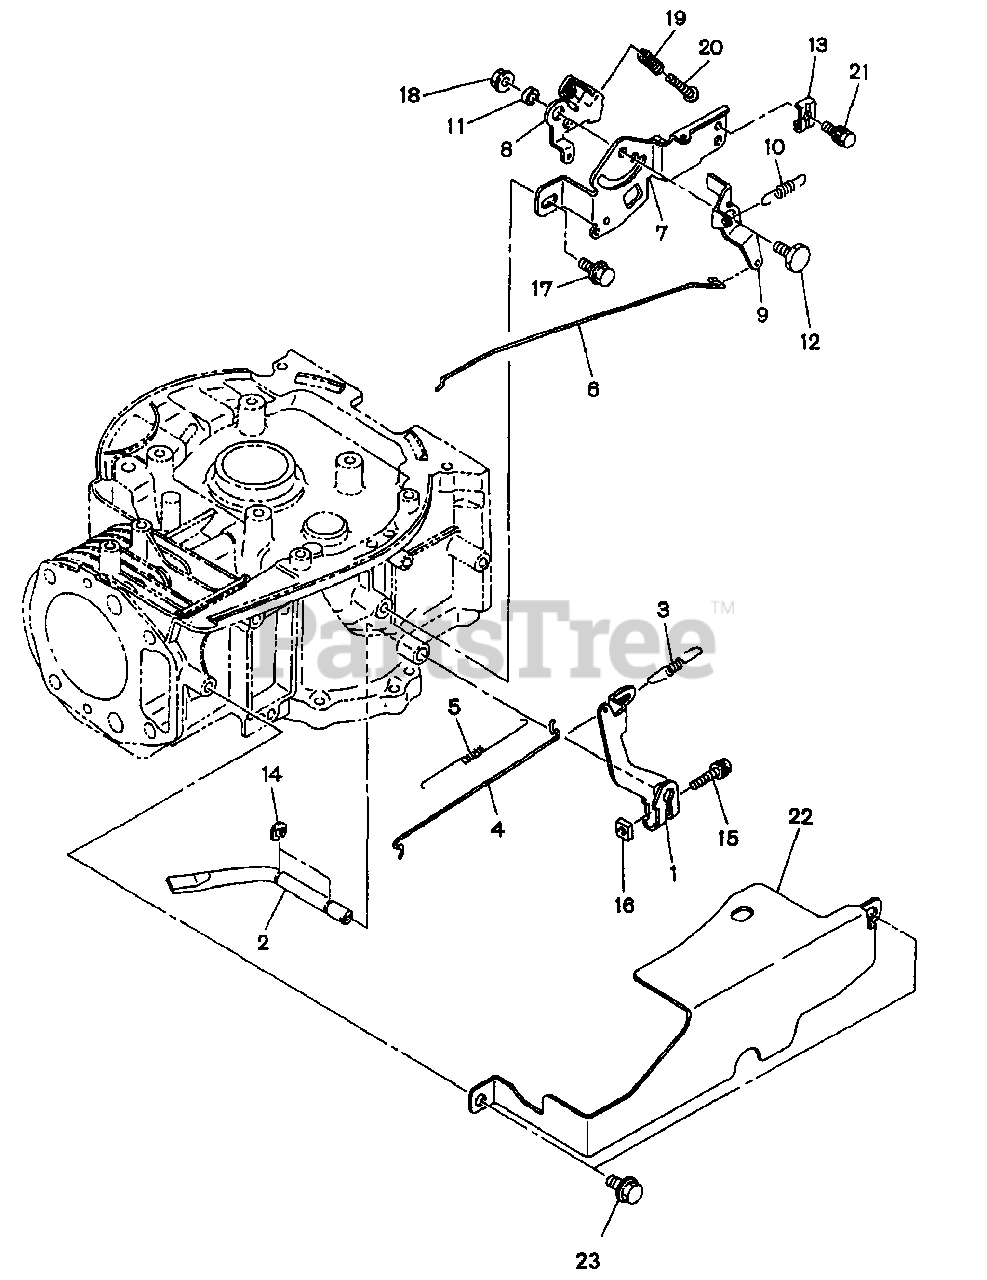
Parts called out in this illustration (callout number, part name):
1	GOVERNOR LEVER
2	GOVERNOR SHAFT
3	GOVERNOR SPRING
4	GOVERNOR ROD
8	SPEED CONTROL LEVER
9	CHOKE LEVER
10	RETURN SPRING
15	BOLT and WASHER ASS'Y
17	FLANGE BOLT
19	SPRING, adjust
20	SCREW, pan head
21	BOLT and WASHER ASS'Y
22	SIDE GUARD (Classic Steel)
23	FLANGE BOLT (Classic Steel)
